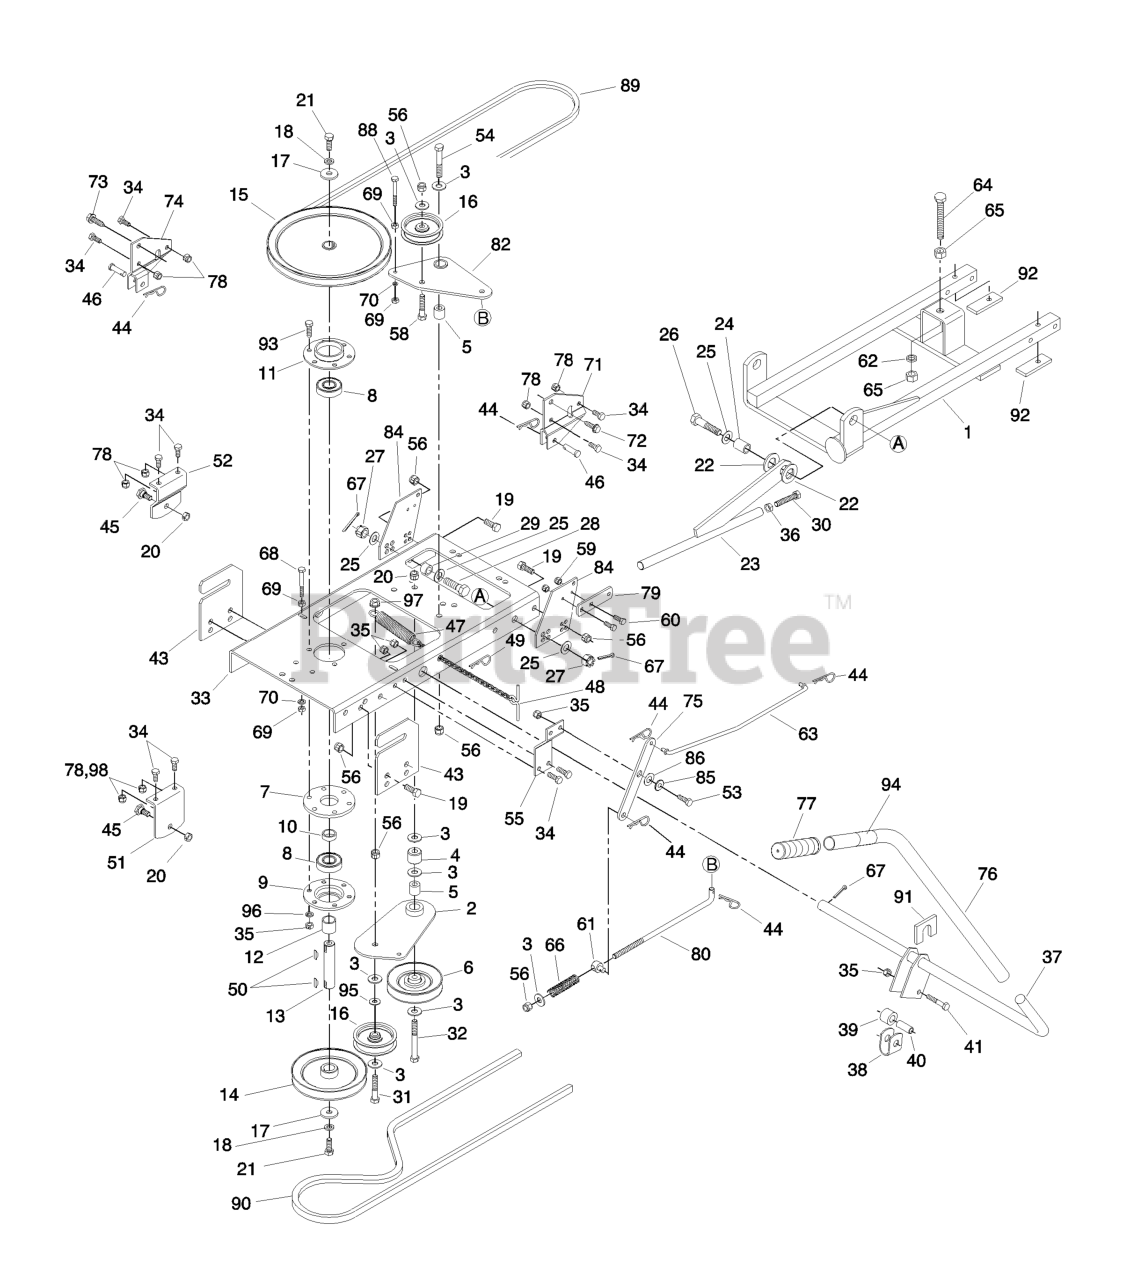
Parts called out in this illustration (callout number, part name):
1	Mounting Frame Assembly
2	Idler Bracket Assembly
3	Washer, 3/8" Flat
4	Spacer, .41 ID x 1.0 OD x .75" L
5	Bushing, .38 ID x .75 OD x .75" L
6	Pulley, V Idler 4" Dia.
7	Spacer, Spindle
8	Bearing, Ball
9	Housing, Bearing
11	Housing, Open Bearing
13	Shaft, .787 Dia. x 3.81 L
14	Pulley, 5-1/2" Dia.
15	Pulley, 9" Dia.
16	Pulley, 3-3/4" Dia.
17	Washer, Flat .406" ID x 1.25" OD
18	Lockwasher, 3/8"
19	Hex Bolt, 3/8-16 x 1"
20	Hex Lock Nut, 3/8-16
21	Hex Bolt, 3/8-24 x 1"
22	Washer, 13/16" x 1-1/2" x .134"
23	Lift Extension Assembly
24	Spacer, .53" ID x .75 OD" x 1.0" L
25	Washer, 17/32" x 1" x 16 Ga.
26	Hex Bolt, 1/2-20 x 2-1/4" Gr. 8
27	Castle Nut, 1/2-20
28	Hex Bolt, 1/2-20 x 1-3/4" Gr. 8
29	Spacer, .53" ID x .75" OD x .50" L
30	Hex Bolt, 3/8-16 x 2" (Full Thread)
31	Hex Bolt, 3/8-16 x 2-1/4"
32	Hex Bolt, 3/8-16 x 3-1/4"
33	Frame, Lift & Pulley
34	Hex Bolt, 5/16-18 x 3/4"
35	Hex Lock Nut, 5/16-18
36	Hex Nut, 3/8-16
37	Lift Bar Assembly
38	Bracket, Lift Stabilizer
39	Spacer, .53 ID x .75 OD x .75 L
40	Spacer, .37 ID x .50 OD x 1.125 L
41	Hex Bolt, 5/16-18 x 1-3/4"
43	Plate, Rear Mounting
44	Pin, Hairpin .09 x 1.58"
45	Shoulder Bolt, 3/8-16 x 5/8"
46	Clevis Pin, 3/8" x 1-1/4"
47	Spring, Extension .75" OD
48	Pull Chain
49	Pin, Haircotter (1/8")
50	Key, (Hi-Pro)
51	Bracket, Rear Hanger (RH)
52	Bracket, Rear Hanger (LH)
53	CAPSCREW, Hex Head, 5/16-18 x 1
54	Hex Bolt, 3/8-16 x 1-1/2"
55	Bracket, Pivot
56	Hex Lock Nut, 3/8-16 (Nylock)
58	Hex Bolt, 3/8-16 x 1-3/4"
59	Hex Lock Nut, 1/4-20 (Nylock)
60	Hex Bolt, 1/4-20 x 1"
61	Anchor, Clutch Rod
62	Lockwasher, 1/2"
63	Rod, Engagement
64	Hex Bolt, 1/2-13 x 3-1/2" Full Thd.
65	Hex Nut, 1/2-13
66	Spring, Coil
67	Pin, Cotter 1/8 x 1-1/4"
68	Hex Bolt, 1/4-20 x 2-3/4"
69	Hex Nut, 1/4-20
70	Lockwasher, 1/4"
71	Front Hanger Bracket (LH)
72	Screw, 5/16-18 x 1" Self Tap
73	Screw, 3/8-16 x 1-1/4" Thd. Form.
74	Front Hanger Bracket (RH)
75	Bell Crank Bracket
76	Handle, Lift
78	Hex Lock Nut, 5/16-18 (Nylok)
79	Bracket, Electric Clutch
80	Rod, Lower Clutch
82	Idler Arm Assembly
84	Plate, Front Mounting
85	Step Bushing
86	Washer, 1/2" x 1" OD x .020"
88	Hex Bolt, 1/4-20 x 1-1/2"
89	Belt, Upper
90	Belt, Lower
91	Lift Bar Bracket
92	Shim Strap
93	Hex Bolt, 5/16-18 x 1-1/4"
94	Label, Handle
95	Spacer, Bushing
96	Lockwasher, 5/16"
97	Hex Lock Nut, 3/8-16 (Washer Face)
